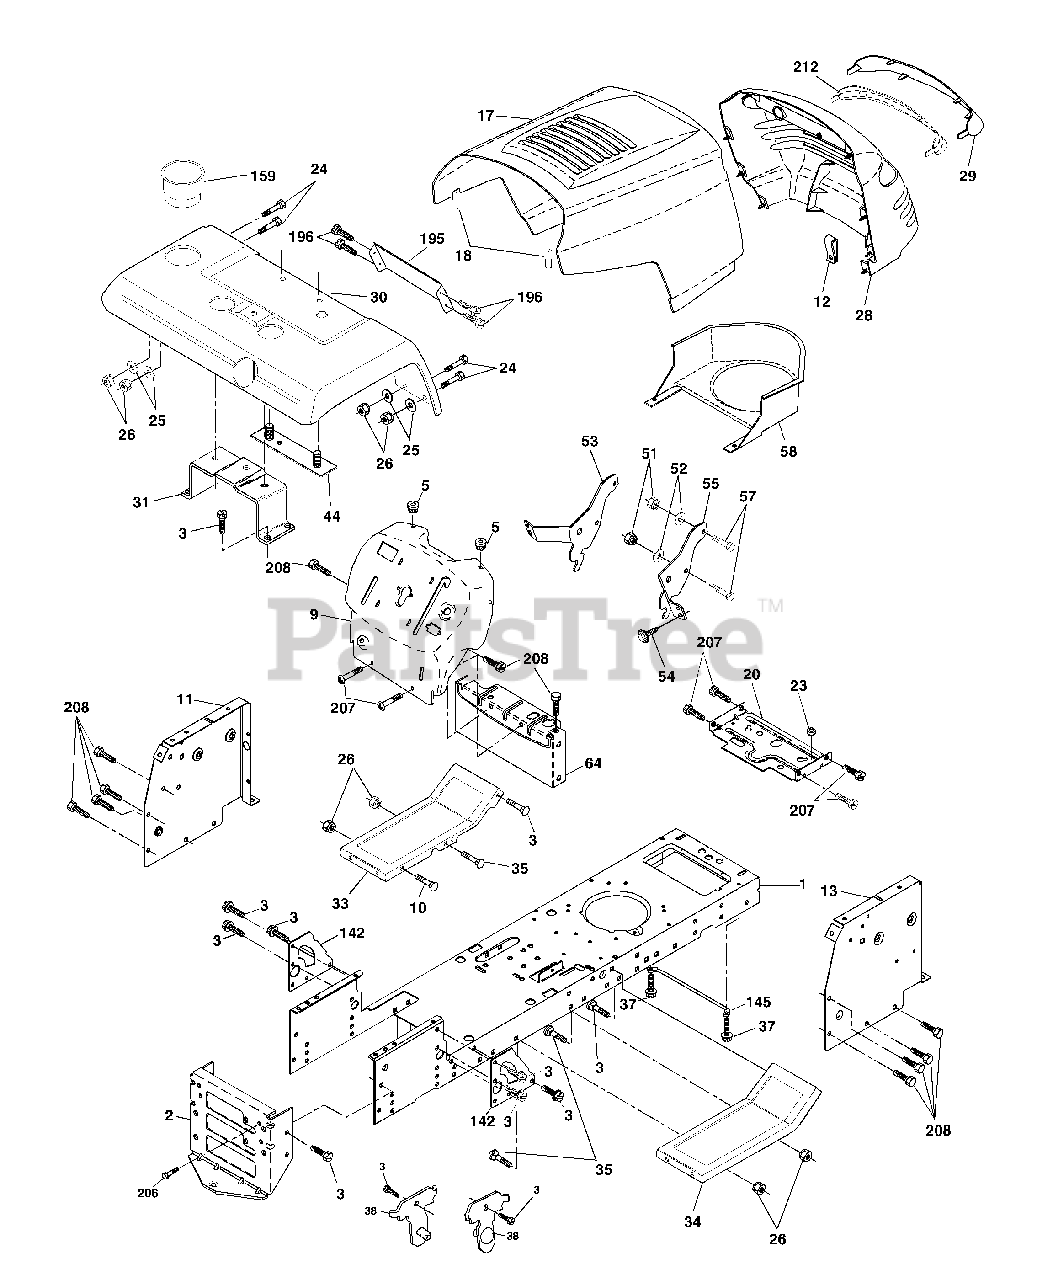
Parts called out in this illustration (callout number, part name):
1	Chassis Stamping
2	Drawbar
3	Screw 3/8-16x3/4
9	Dashboard
10	Bolt Rdhd Sqnk 3/8-16 Unc x 1
11	Panel Dash Lh
12	Clip Tinnerman Grille
13	Panel Dash Rh
17	Hood
20	Plate Mtg Battery/Fuel Tank
24	Bolt 3/8-16 Unc x 1 Gr. 5
25	Washer 13/32 x 13/16 x 12 Ga.
26	Nut Lock w/Insert 3/8-16 UNC
28	Grille Lens Asm
29	Lens
30	Fender
31	Bracket
33	Foot Rest, L.H.
34	Foot Rest, R.H.
35	Bolt Rdhd Sht Sqnk 3/8-16 x 3/4
37	Screw Thdrol 5/16-18 x 1/2
38	Bracket Asm Pivot Mower Rear
44	Strap Asm. Fender
51	Nut Lock w/Insert 1/4-20
52	Washer 9/32 x 7/8 x 16 Ga.
53	Bracket Grille Lh
54	Screw Hex Wshd 8-18 x 7/8
55	Bracket Grille Rh
57	Bolt Fin Hex 1/4-20 Unc x 3/4
64	Dash Lower Stlt
142	Plate Reinforcement Stlt
145	Rod Pivot Chassis Hood
159	Cupholder YTGT Grey
195	Panel Pnt Fender YT/GT
196	Screw Tap Tite 1/4-20 x 1/2
206	Bolt Shoulder 5/16-18 TT
207	Screw Thdrol 5/16-18 x 1/2 TYTT
208	Screw Thdrol 3/8-16 x 1/2 Ty-TT
212	Insert Lens Reflect
